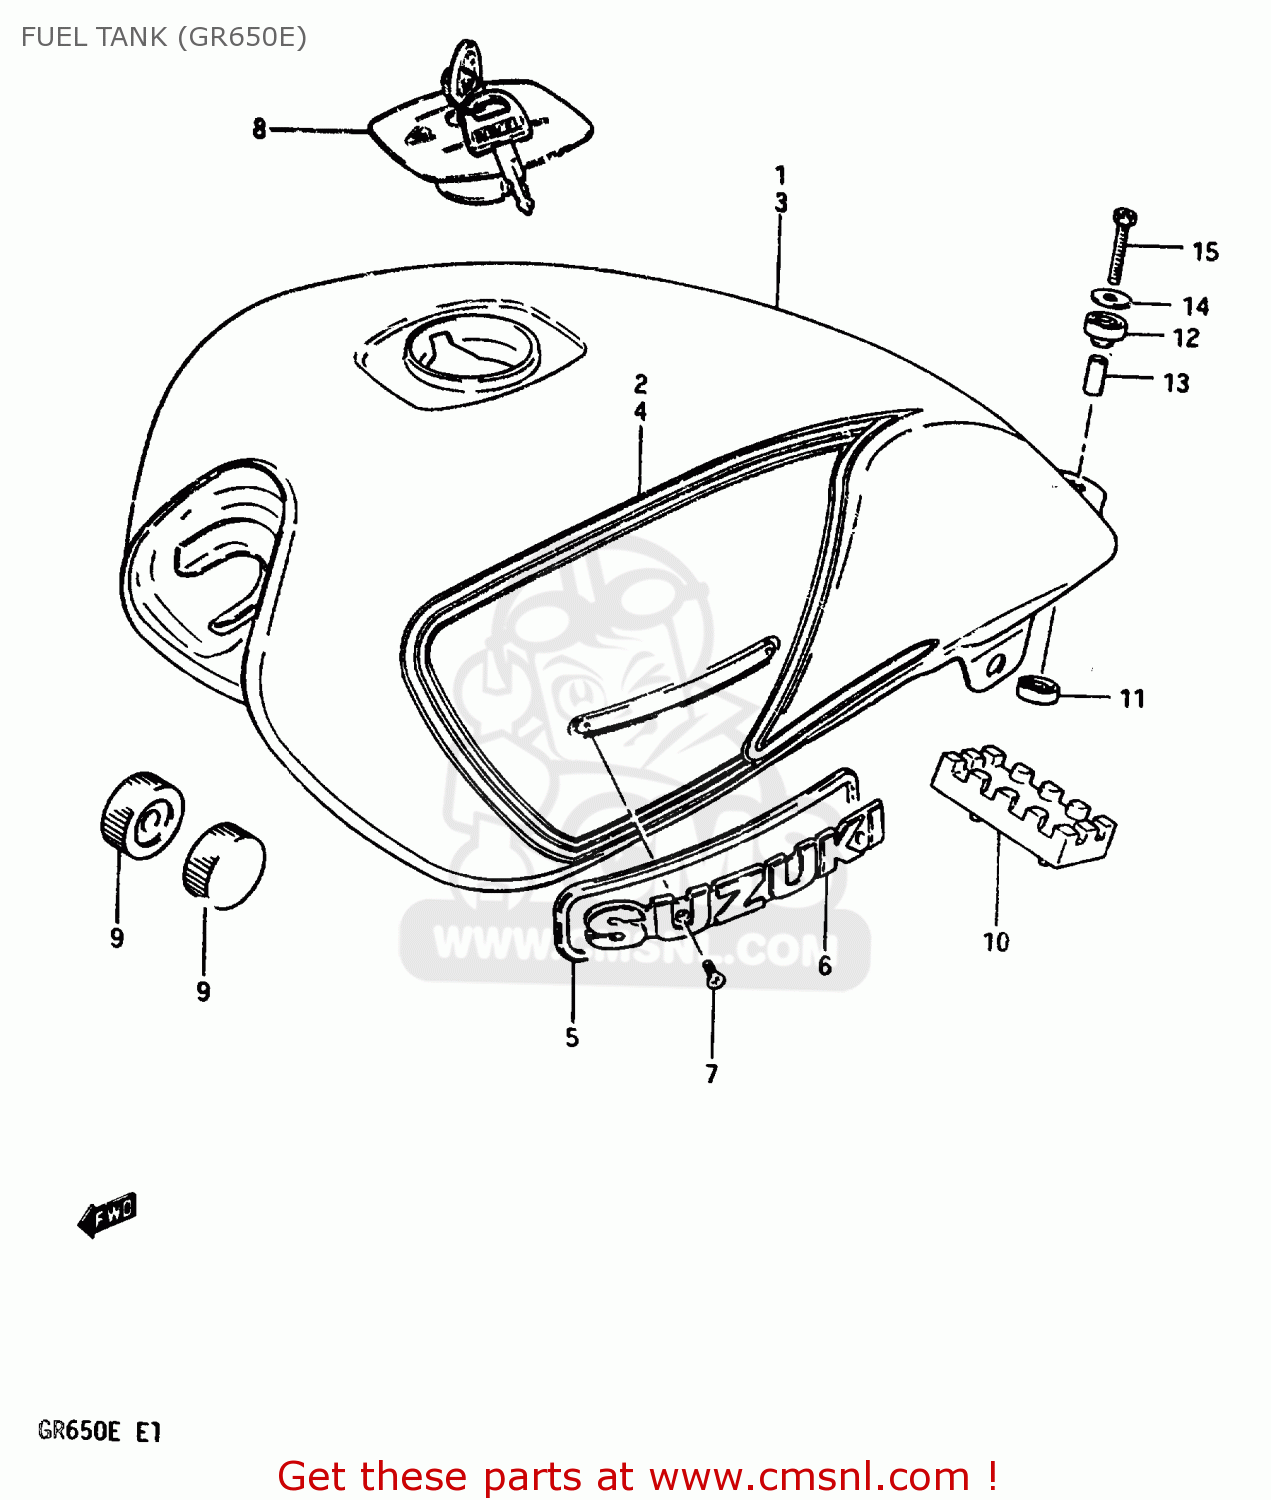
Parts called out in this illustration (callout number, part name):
1	TANK, FUEL
2	TAPE SET, FUEL TANK
3	TANK, FUEL
4	TAPE SET, FUEL TANK
5	CUSHION
6	EMBLEM,FUEL TANK
7	SCREW 3X6
8	CAP SET,FUEL TANK
9	CUSHION
10	CUSHION,FUEL TANK CTR
11	CUSHION
12	CUSHION
13	SPACER (6.4X9X20)
14	WASHER (6.5X24X1.6)
15	BOLT
